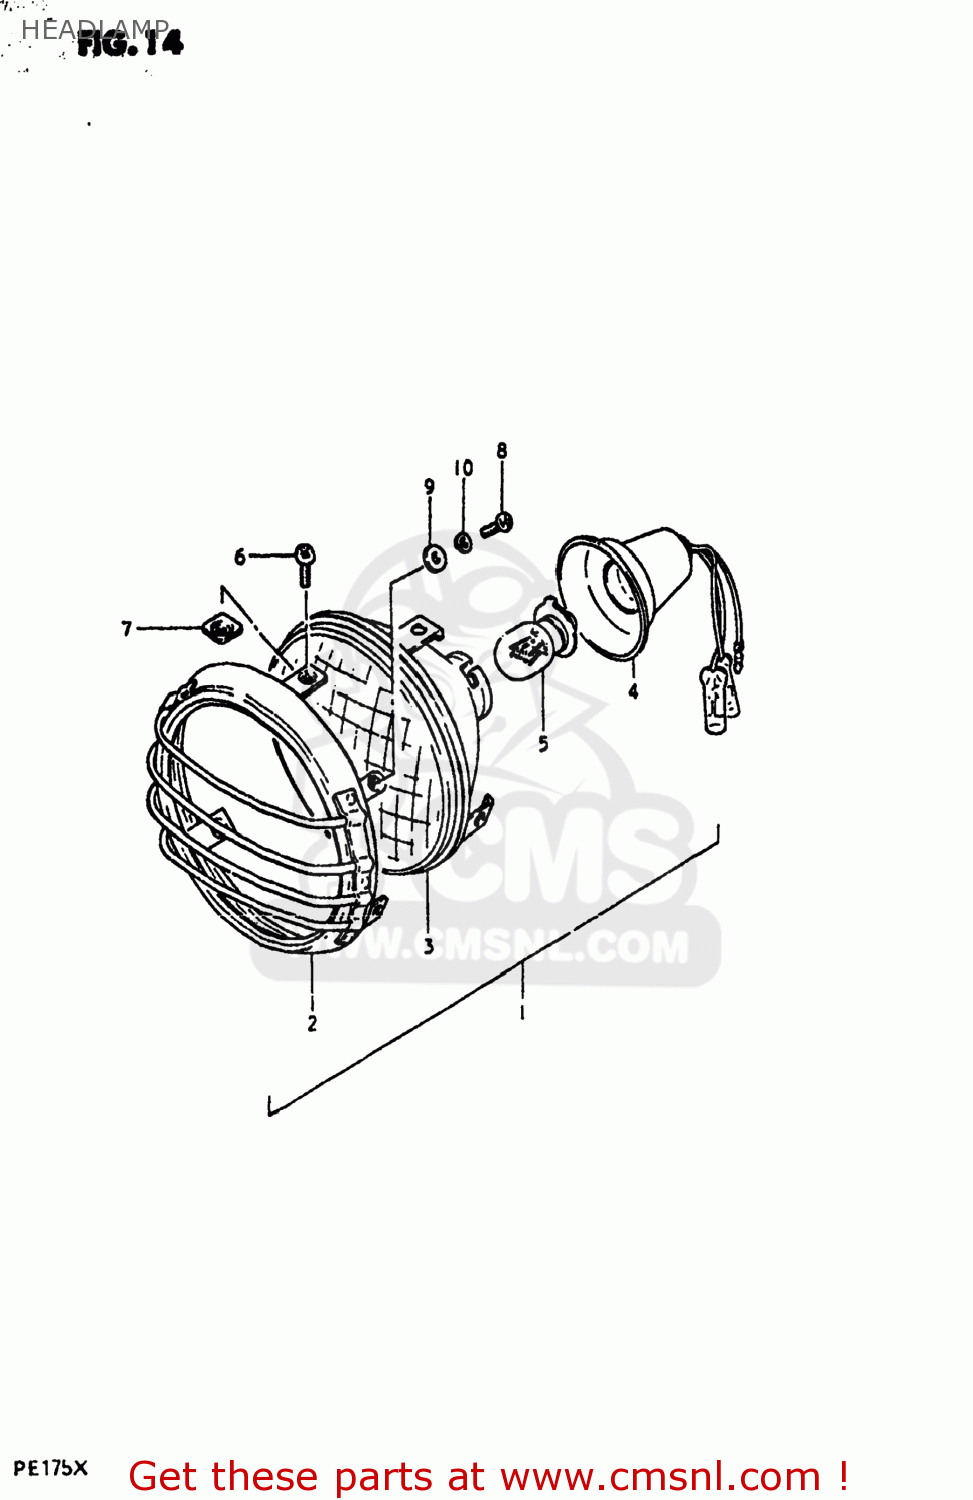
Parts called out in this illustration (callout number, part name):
1	HEADLAMP ASSEMBLY
2	RIM,HEADLAMP
3	LAMP UNIT
4	SOCKET,HEADLAMP
5	BULB(6V15/15W/STANLEY,A3598HA)
6	SCREW
7	NUT
8	SCREW
9	WASHER
10	LOCK WASHER
